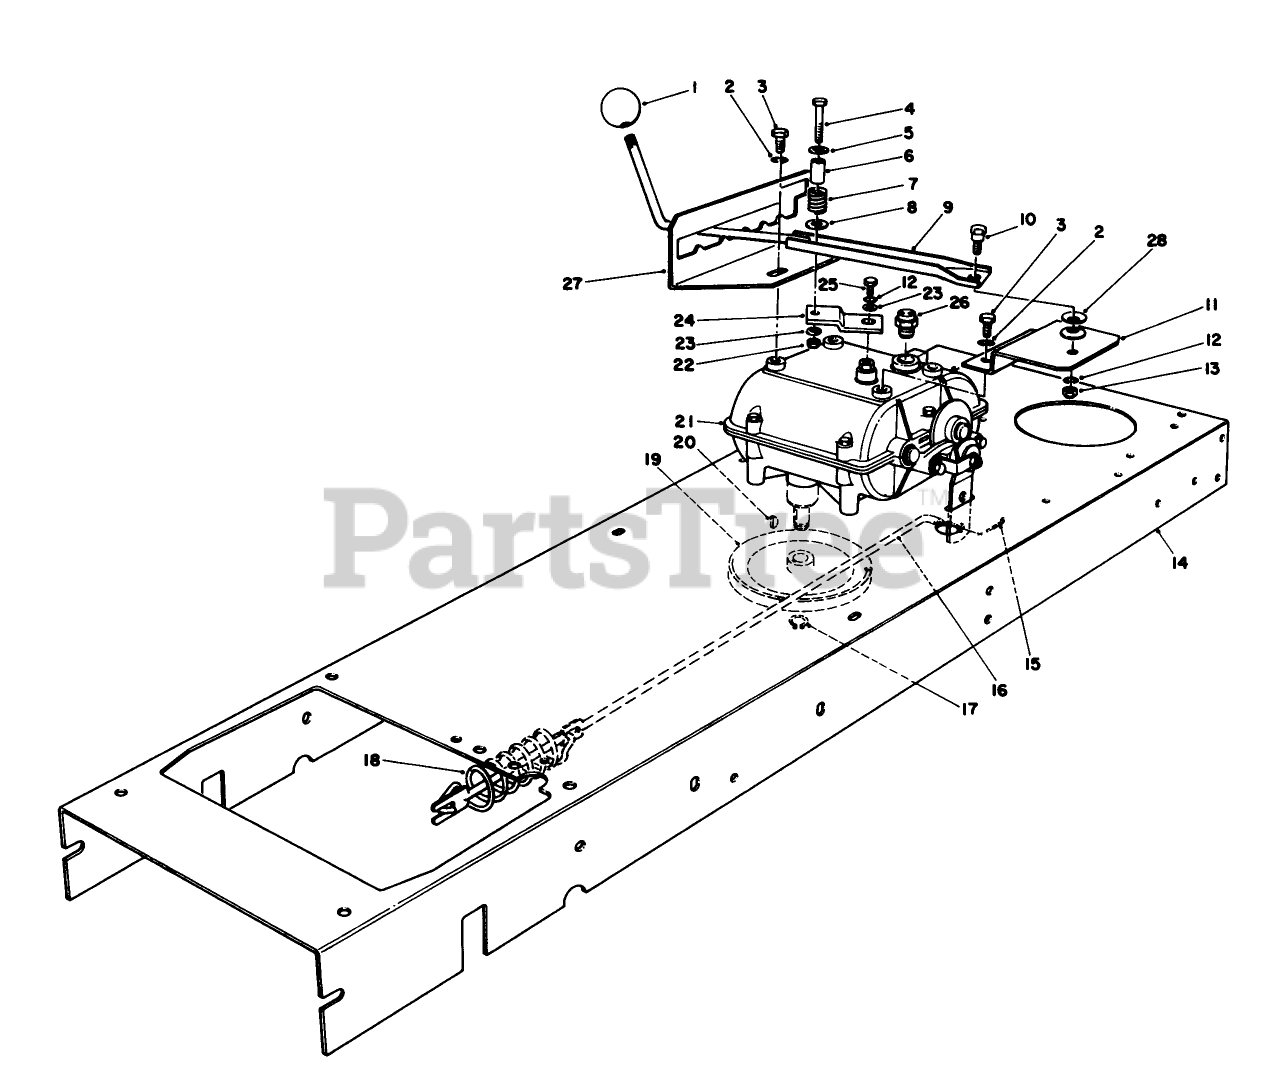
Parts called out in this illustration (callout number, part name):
2	WASHER-LOCK
3	SCREW-THD ROLL, HWH
4	SCREW-HH
5	WASHER-FLAT
6	SPACER-SPLIT
7	SPRING-COMPRESSION
8	WASHER-FLAT
10	SCREW-SHOULDER
11	SHIFT MTG BRKT
12	WASHER-LOCK
13	NUT-LOCK, NI
15	PIN-COTTER
16	BRAKE ROD
17	RING-SNAP, EXTERNAL
19	PULLEY
20	KEY-WOODRUFF
22	NUT-LOCK, CONE
23	WASHER-FLAT
25	SCREW-HH
26	NEUTRAL SWITCH
28	WASHER-BELLEVILLE
